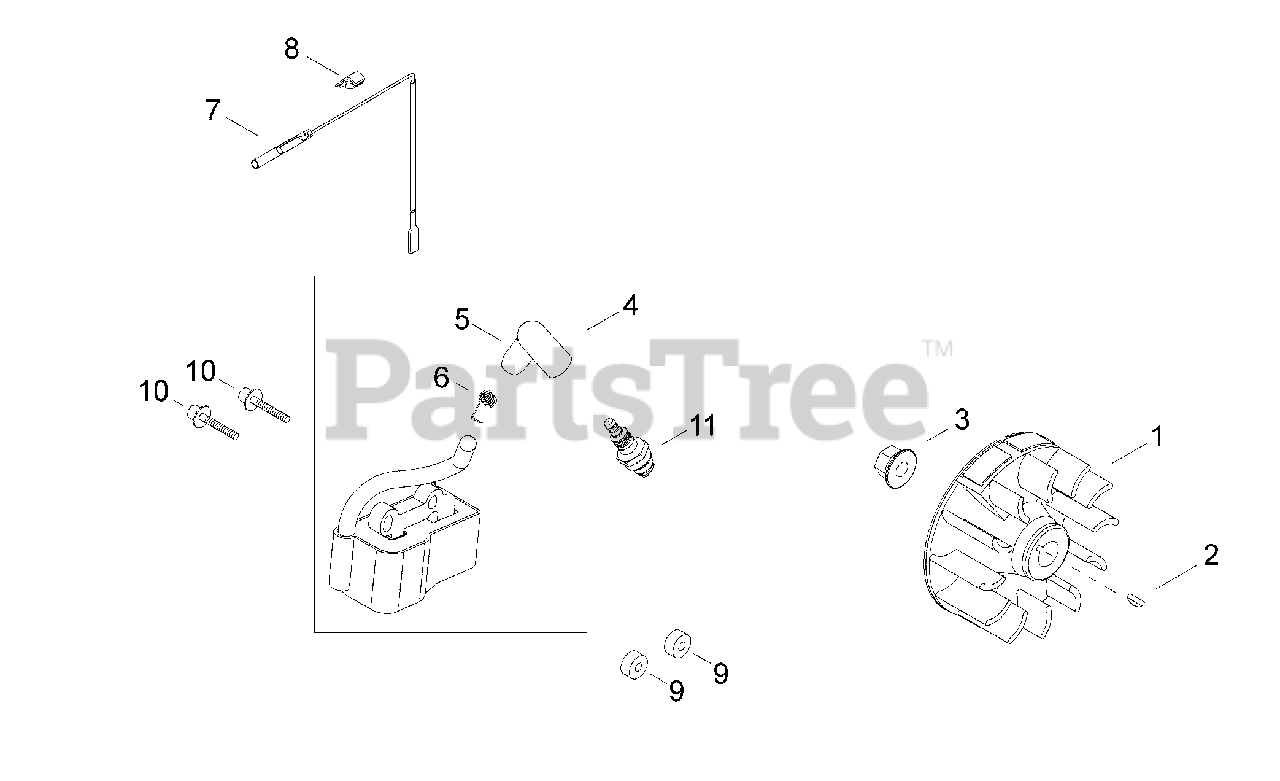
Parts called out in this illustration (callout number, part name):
1	FLYWHEEL
2	KEY, WOODRUFF 3×10
3	NUT M8
4	COIL ASSY, IGNITION
5	CAP, SPARK PLUG
6	TERMINAL, SPARK PLUG
7	LEAD - IGNITION
8	GROMMET, LEAD
9	INSULATOR 4.2×11×6
10	BOLT M4×26
11	SPARK PLUG - CMR5H
